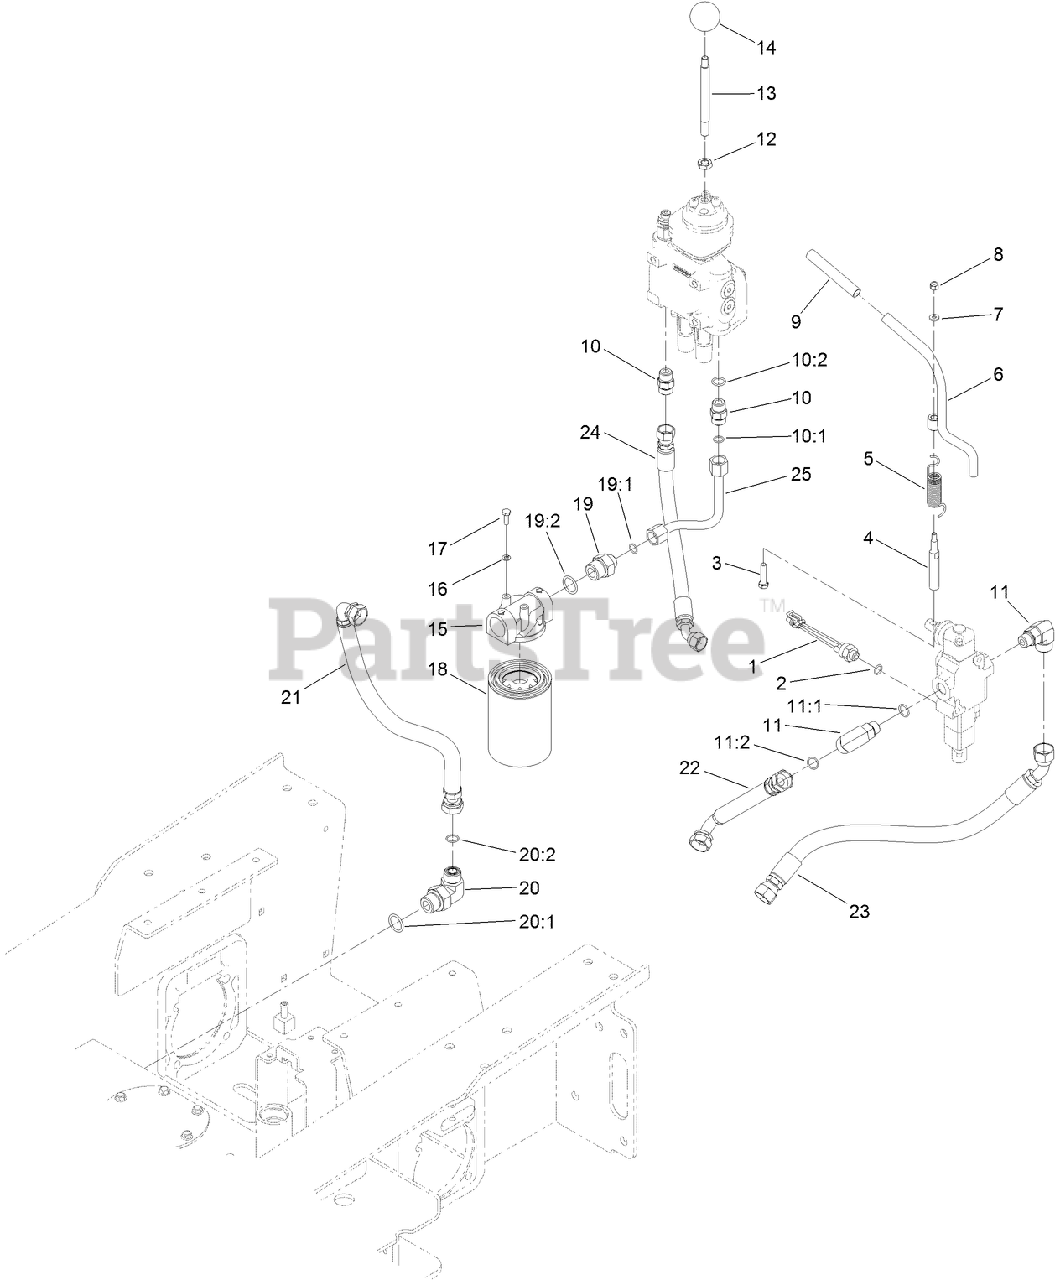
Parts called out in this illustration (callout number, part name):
1	SWITCH-BALL
2	O-RING
3	SCREW-HH
4	SPACER-HIFLO
5	SPRING-TORSION
6	LEVER-AUXILIARY
7	WASHER-FLAT
8	NUT-LOCK, NI
9	GRIP-RUBBER
10	FITTING-STRAIGHT
10:1	O-RING
10:2	O-RING
11	FITTING-ELBOW, 90 DEG
11:1	O-RING
11:2	O-RING
13	SHAFT-HANDLE, LOADER
15	HEAD-FILTER
16	WASHER-LOCK
17	SCREW-HH
18	FILTER-OIL
19	FITTING-STR
19:1	O-RING
19:2	O-RING
20	FITTING-ELBOW 90
20:1	O-RING
20:2	O-RING
21	HOSE-HYD
22	HOSE-HYD
23	HOSE-HYD
24	HOSE-HYD
25	TUBE-HYD
